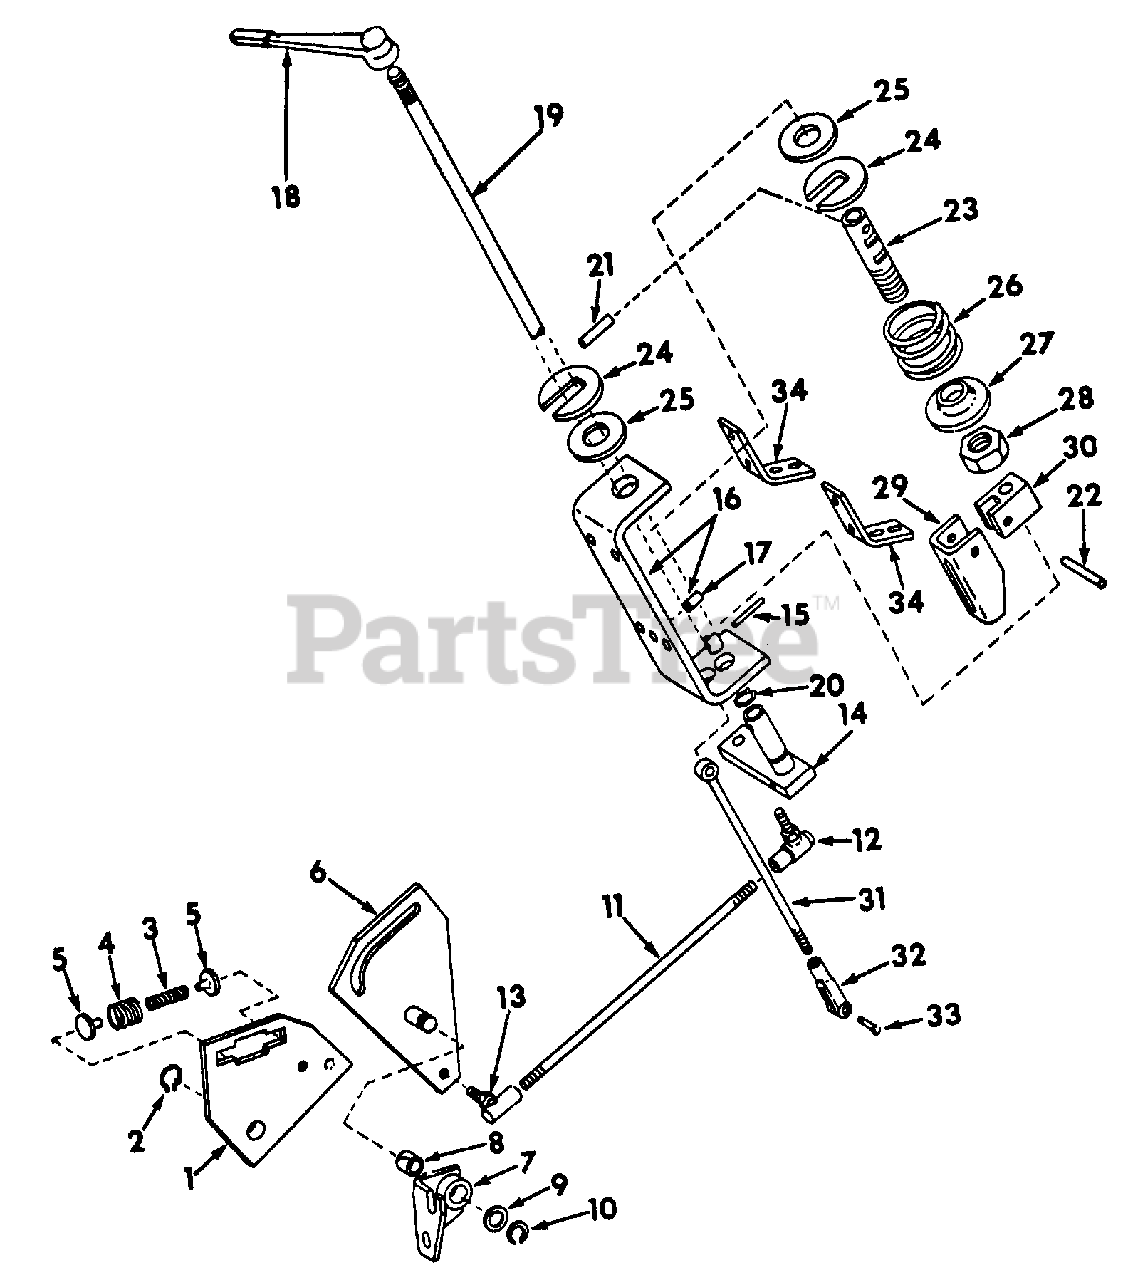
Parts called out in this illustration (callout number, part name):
1	Plate Assy, Damper Spring
2	Ring, Damper Plate Retaining
3	Spring, Damper Light
4	Spring, Damper Heavy
5	Pin, Damper Spring Guide
6	Cam Assy, Speed Control
7	Bracket Assy, Cam Pivot
8	Bushing, Cam Pivot
9	Washer, Cam Retaining
10	Ring, Cam Retaining
11	Rod, Speed Control Connection
12	Joint, 5/16-24 X 1-1/2 C-Z RH Thd Ball
13	Joint, 5/16-24 X 1-1/2 C-Z LH Thd Ball
14	Lever Assy, Speed Control
15	Pin, 1/4 X 1-3/4 Dowel
16	Bracket Assy, Hand Control Mounting
17	Pin, 1/4 X 1/2 Dowel
18	Handle, Speed Control
19	Rod, Speed Control
20	Ring, Lever Retaining
21	Pin, 1/4 X 1-1/4 Dowel
22	Pin, 1/4 X 1-1/2 Hv Coil Spring
23	Shaft, Frictional Adjusting Column
24	Retainer, Spring
25	Washer, Frictional Disc
26	Spring, Frictional
27	Washer, Frictional Spring Guide
28	Nut, 7/8-14 Esna Stop
29	Channel, Speed Control Centering Cam
30	Swivel, Cam Centering Actuator
31	Rod Assy, Centering Cam Actuating
32	Clevis, 1/4-28 X 2 Light Adj Rod End
33	Pin, 1/4 X 51/64 C-Z Rod End
34	Brace, Control Bracket Reinforcement
